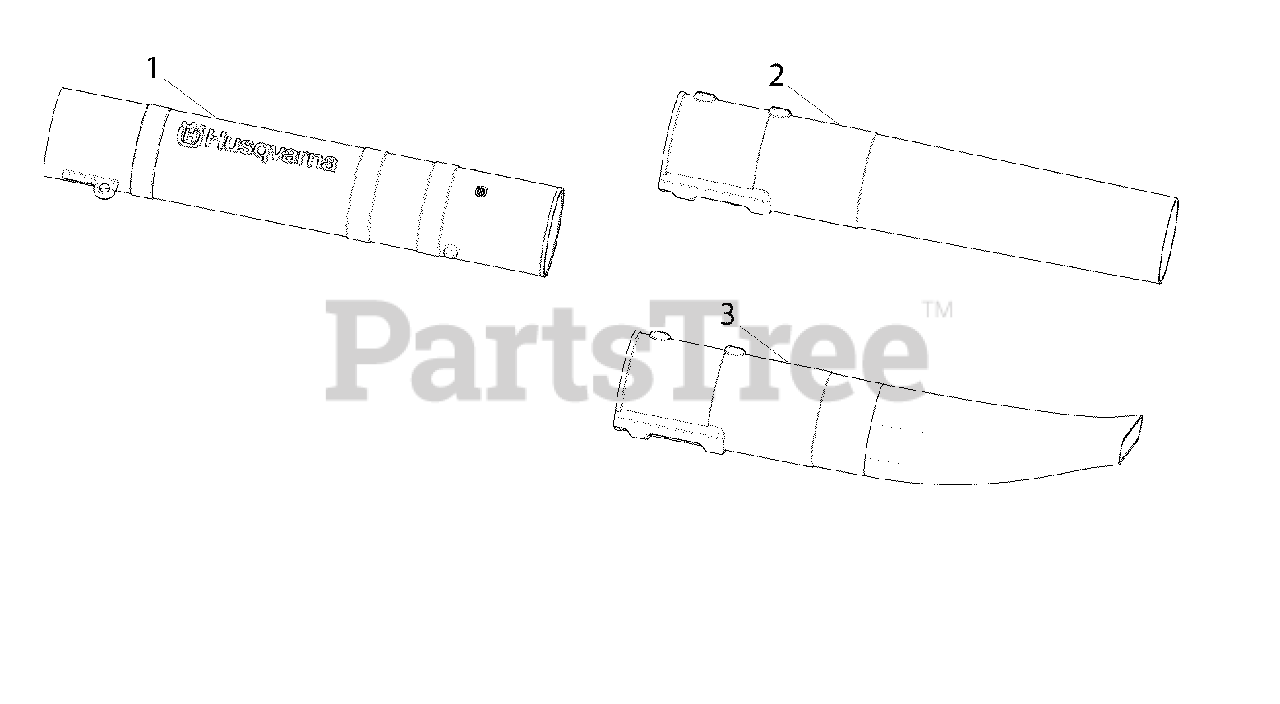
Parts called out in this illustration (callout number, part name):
1	Assy - Tube - Upper Blower w/barrier
2	Tube - Lower Blower
3	Flare - Lower Blower tube
